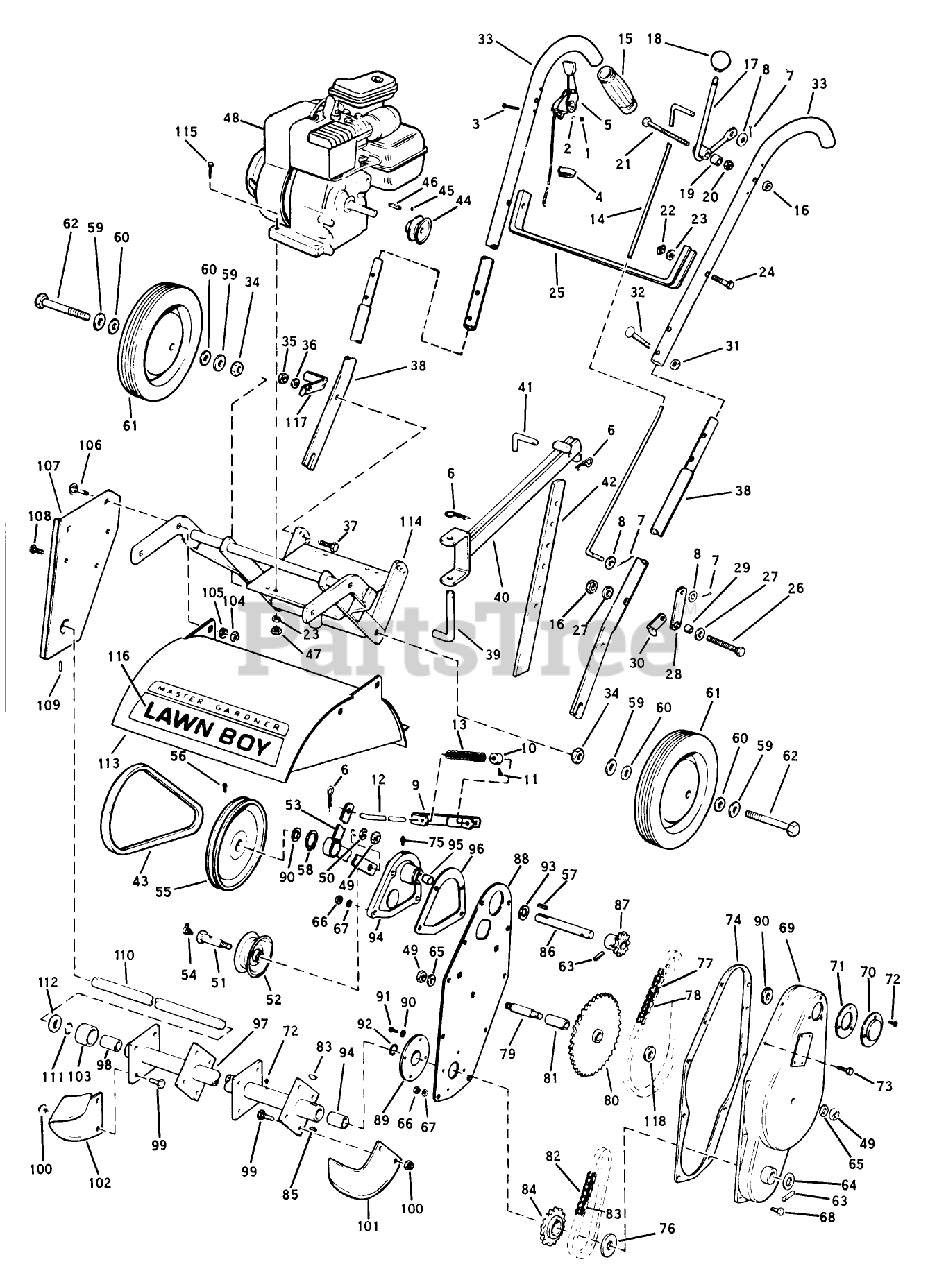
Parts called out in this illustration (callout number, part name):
2	Lockwasher
3	Machine Screw #8-32 x 1-1/2 Lg.
4	Cable Clip
5	Throttle Control Assembly
9	Spring Bracket Assembly
11	Set Screw
12	Engine 8 H.P.
17	Control Lever Assembly
28	Shifting Lever
32	Square Nut 5/16-18
34	Hex Jam Nut 1/2-13
35	LOCKNUT
37	Capscrew 3/8-16 x 1-1/4 Lg.
38	Handle Bar Tube Assembly
40	Beam Assembly
41	Selector Pin
42	Depth Bar
48	Engine (B S)
52	Idler Pulley
56	Set Screw
60	Rubber Washer
61	Wheel Assembly 10 x 1.75
62	Hex Head Capscrew 1/2-13 NC x 4 Lg.
63	Roll Pin
65	Lockwasher, Shakeproof
67	WASHER-LOCK
70	Cover Plate
71	Gasket (Cover Plate to Cover)
73	Capscrew (Cover Assy. to Sleeve Assy.)
75	Grease Fitting
76	Thrust Washer
77	Chain Connector Links
79	Intermediate Shaft
80	Sprocket Cluster Assy
81	Bushing
85	Woodruff Key
86	Input Shaft
87	Input Sprocket Hub Assembly
88	Back Plate Assembly
91	Self-Tapping Screws (Seal to Back Plate)
92	Clamp, Seal
94	Sleeve Bushing Assy.
97	Rotor Tube Assembly
102	Tine LH
104	Nut-Hex
105	WASHER, LOCK
106	Carriage Bolt 3/8-16 x 1 Lg.
107	Side Plate Assembly
108	Screw (Side Plate to Hood)
109	Roll Pin
110	Rotor Shaft
113	Hood Assembly
114	Frame Assembly
116	Decal-"LAWN BOY"
